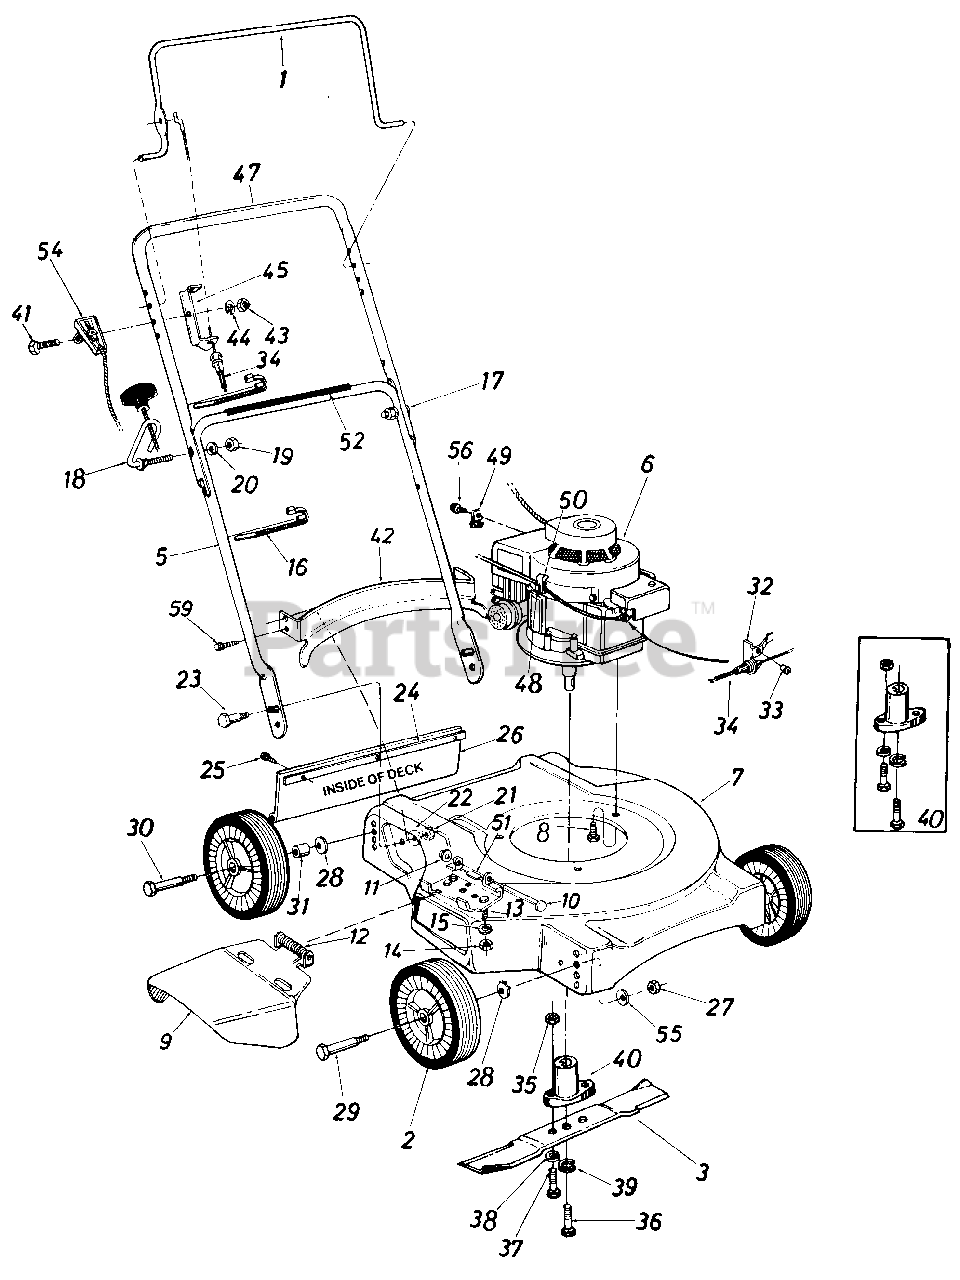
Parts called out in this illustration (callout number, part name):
1	Control Handle
2	Plastic Wheel Ass'y.
3	20" Blade
5	Lower Handle
6	Engine
9	Chute Deflector Ass'y.
10	Pivot Pin
11	Cap Speed Nut 1/4" Rod
12	Torsion Spring
13	Hex Bolt 1/4-20 X .50" Lg.
14	Hex Nut 1/4-20 Thd.
15	L-Wash. 1/4" I.D.
16	Cable Tie
17	Curved Carriage Bolt 5/16-18 x 1.38" Lg.
18	Rope Guide Bolt
19	Hex Nut 5/16-18 Thd.
20	L-Wash. 5/16" I.D.
21	Hex Ins. L-Nut 5/16-18 Thd.
22	Bell-Wash. .345" I.D. x .88" O.D.
23	Shld. Bolt .437" Dia. x .180" Lg.
24	Retainer Strip
25	Hex Wash. Hd. Self-Tap Scr. 1/4" x.62" Lg.
26	Rear Flap Ass'y.
27	Hex Nut 3/8-16 Thd.
28	Bell-Wash. .400" I.D. x .88" 0.D.
29	Shld. Bolt
30	Shld. Bolt
31	Spacer
32	Cable Bracket
33	Pop Rivet .156" Dia. x .379
34	Control Cable 43.0" Lg.
35	Hex Nut 5/16-24 Thd.
36	Hex Bolt 3/8-24 x 1.00" Lg.
37	Hex Bolt 5/16-24 x 1.00" Lg.
38	L-Wash. 5/16" I.D.
39	L-Wash. 3/8" I.D. Heavy Duty
40	Blade Adapter Kit
41	Hex Bolt 1/4-28 x 1.75" Lg.
42	Rear Baffle
43	Hex Nut 1/4-28 Thd.
44	L-Wash. 1/4" I.D.
45	Cable Mounting Brkt.
47	Upper Handle
48	Hex B-Tap Scr. #10 x .38" Lg.
49	Casing Clamp
50	Casing Clamp
51	Hinge Plate
52	Instruction Label Handle
54	Throttle Control Ass'y. Comp. B&S
55	Bell-Wash. .39" I.D. x 1.13" O.D.
56	Hex AB-Tap Scr. #8 x .38" Lg.
59	Hex Tap Screw #10 x .50" Lg.
